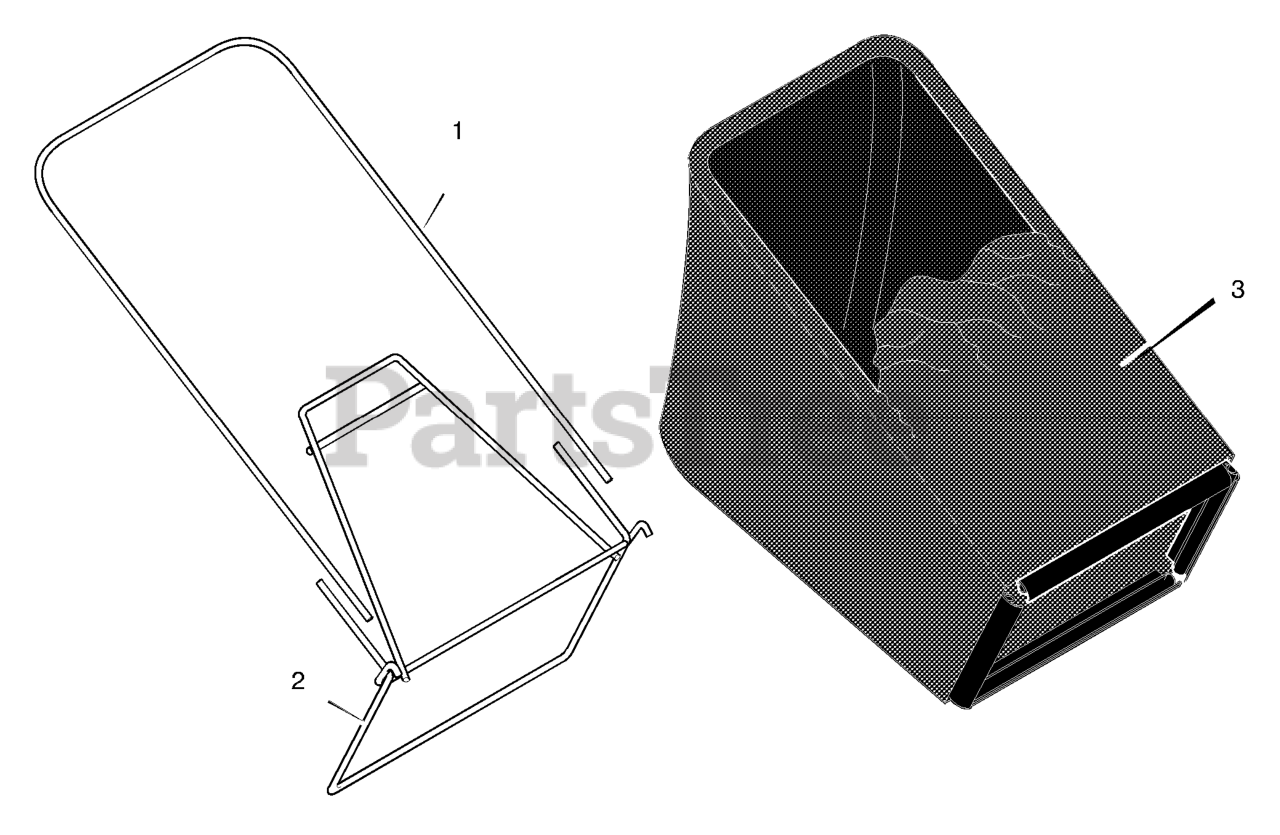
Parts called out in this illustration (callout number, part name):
1	Tube, Bag
2	Frame Assembly
3	Bag, Cloth - Gray
